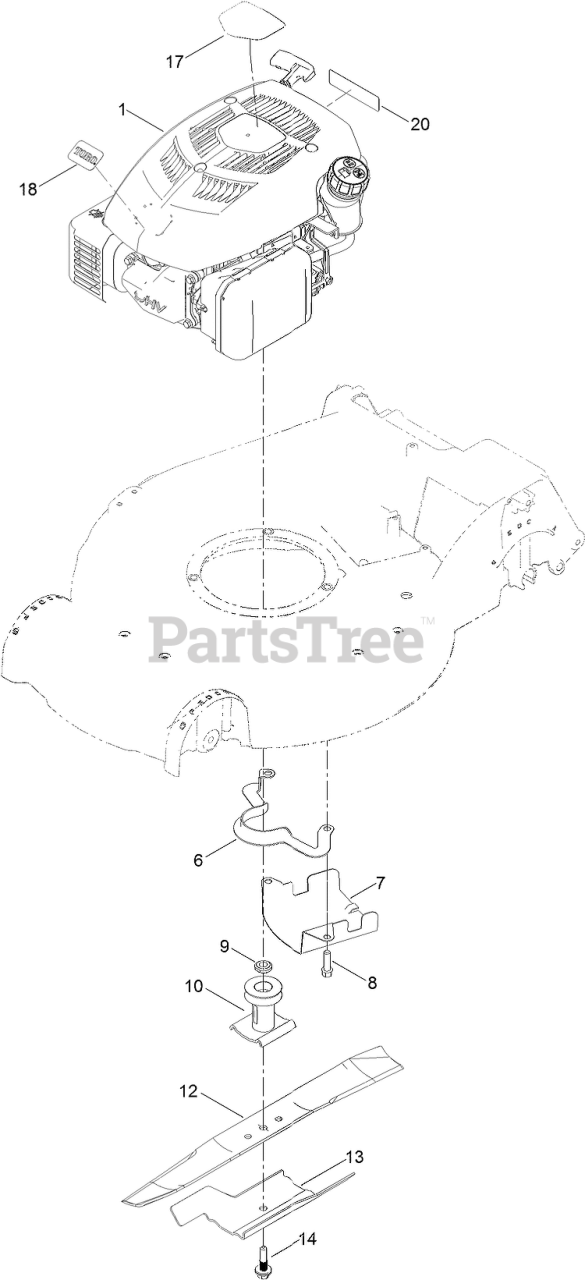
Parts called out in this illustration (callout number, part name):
1	ENGINE-1P65F-2
6	GUIDE-BELT
7	SHIELD-GRASS
8	SCREW-TAPTITE
9	SPACER-DRIVER
10	DRIVER-BLADE
13	ACCELERATOR-BLADE
14	BOLT-BLADE
17	DECAL-SHROUD
20	DECAL-ARRESTER, SPARK
